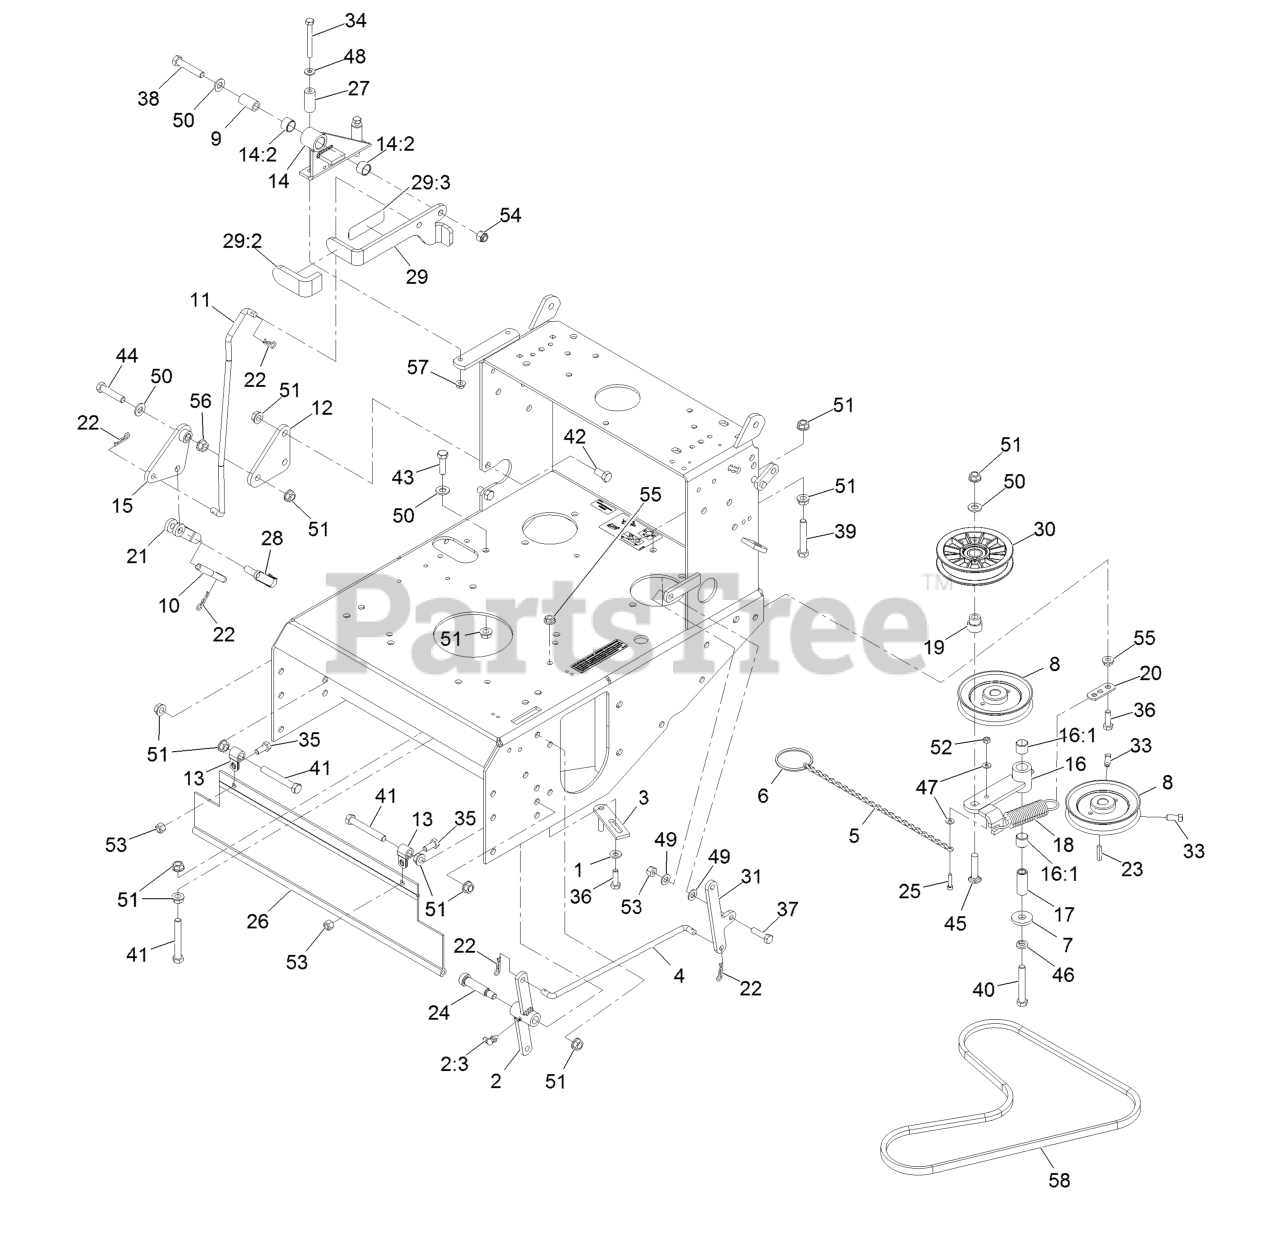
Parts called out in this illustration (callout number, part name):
1	Washer-Spring Disc 5/16
2	Bellcrank ASM
2:3	Zerk-90deg 1/4-28
3	Guide-Belt
4	Linkage-Engage, Blade
5	Chain-Link, Twist
6	Ring-Split
8	Sheave ASM
9	Bushing-Pivot
10	Linkage-Lower
11	Linkage-Upper
12	Bellcrank
13	Clip-Loom
14	Bracket ASM
14:2	Sleeve-Bushing
15	Bellcrank ASM
16	Idler Arm ASM
16:1	Sleeve-Bearing
17	Bushing
18	Spring-Extension
19	Bushing-Idler
20	Anchor-Spring
21	Yoke-Linkage, Brake
22	Hairpin-Cotter
23	Key-5Mm X 5Mm X 25Mm
25	Screw-HSH #10-24 X 7/8
26	Shield-Drag
28	Pin-Clevis Spring 3/8
29	Lever, Park Brake W/Decals
29:2	Grip-Lever
29:3	Decal-Parking Brake
30	Pulley-Idler, Flat
31	Bellcrank
33	Screw-Set, SQH 5/16-18 X 3/4
34	Screw-HH
35	Screw-HH 5/16-18 X 3/4
36	Screw-HH 5/16-18 X 1
37	Screw-HH 5/16-18 X 1 1/4
38	Screw-HH 3/8-16 X 2
39	Screw-HH 3/8-16 X 2 1/4
40	Screw-HH 3/8-16 X 2 1/2
41	Screw-HH 3/8-16 X 2 3/4
42	Screw-HH 3/8-16 X 3/4
43	Screw-HH 3/8-16 X 1 1/4
44	Screw-HH 3/8-16 X 1 3/4
45	Bolt-Carriage 3/8-16 X 1 3/4
46	Washer-Lock 3/8 Heavy
47	Washer-#10 Std
48	Washer-1/4 SAE
49	Washer-5/16 SAE
50	Washer-3/8 SAE
51	Nut-Whizlock 3/8-16
52	Nut-Nyloc #10-24
53	Nut-Nyloc 5/16-18
54	Nut-Nyloc 3/8-16
55	Nut-Whizlock 5/16-18
56	Nut-3/8-16 Flanged Side Lock
57	Nut-Whizlock 1/4-20
58	Belt-Cog
